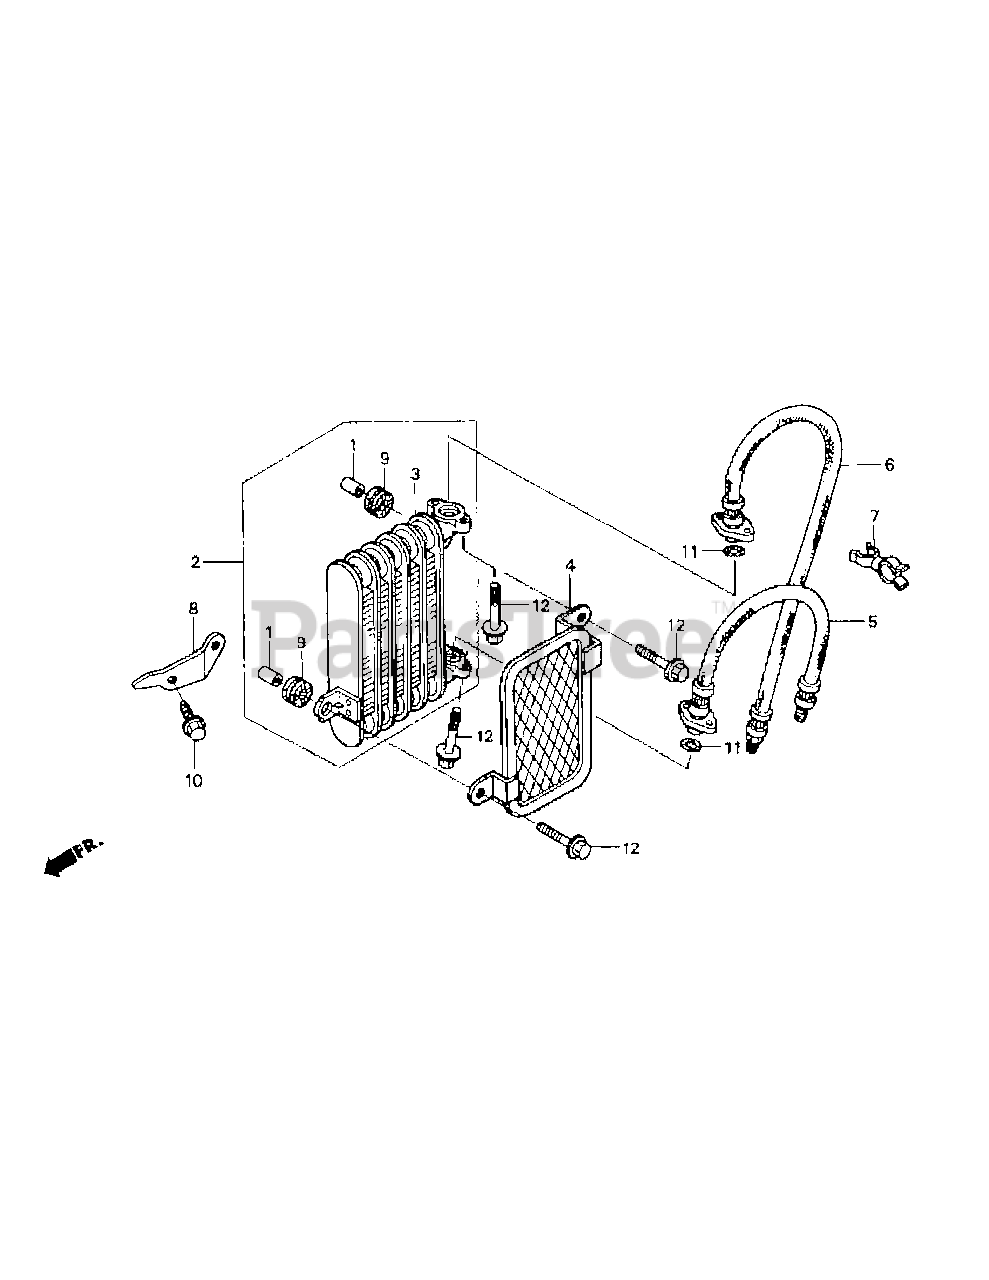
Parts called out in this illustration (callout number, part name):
1	Collar (12mm)
2	Oil Cooler Assy.
3	Oil Cooler
4	Oil Cooler Grille
5	Oil Hose A
6	Oil Hose B
7	Pipe Clamp (15.5x13)
8	Oil Cooler Bracket
9	Radiator Mounting Rubber
10	Flange Bolt (6x14)
11	O-Ring (10x2.6)
12	Flange Bolt (6x22)
